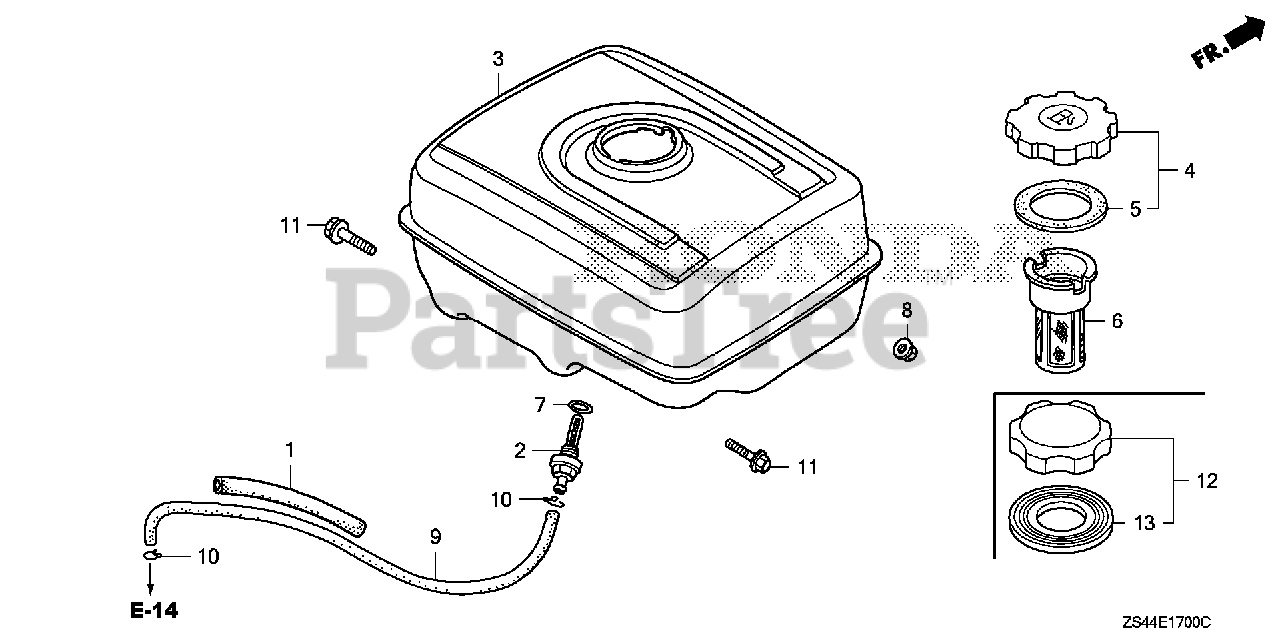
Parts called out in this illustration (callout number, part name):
1	RUBBER, SUPPORTER (107MM)
2	JOINT, FUEL TANK
3	TANK, FUEL *R280* (POWER RED)
4	CAP, FUEL FILLER (BLACK)
5	GASKET, FUEL FILLER CAP (39X58X3)
6	FILTER, FUEL
7	O-RING (13.5X1.5) (ARAI)
7	O-RING (14MM) (NOK)
8	NUT, FLANGE (8MM)
9	BULK HOSE, FUEL (4.5X3000) (4.5X235)
10	CLIP, TUBE (B8)
11	BOLT, FLANGE (8X25)
